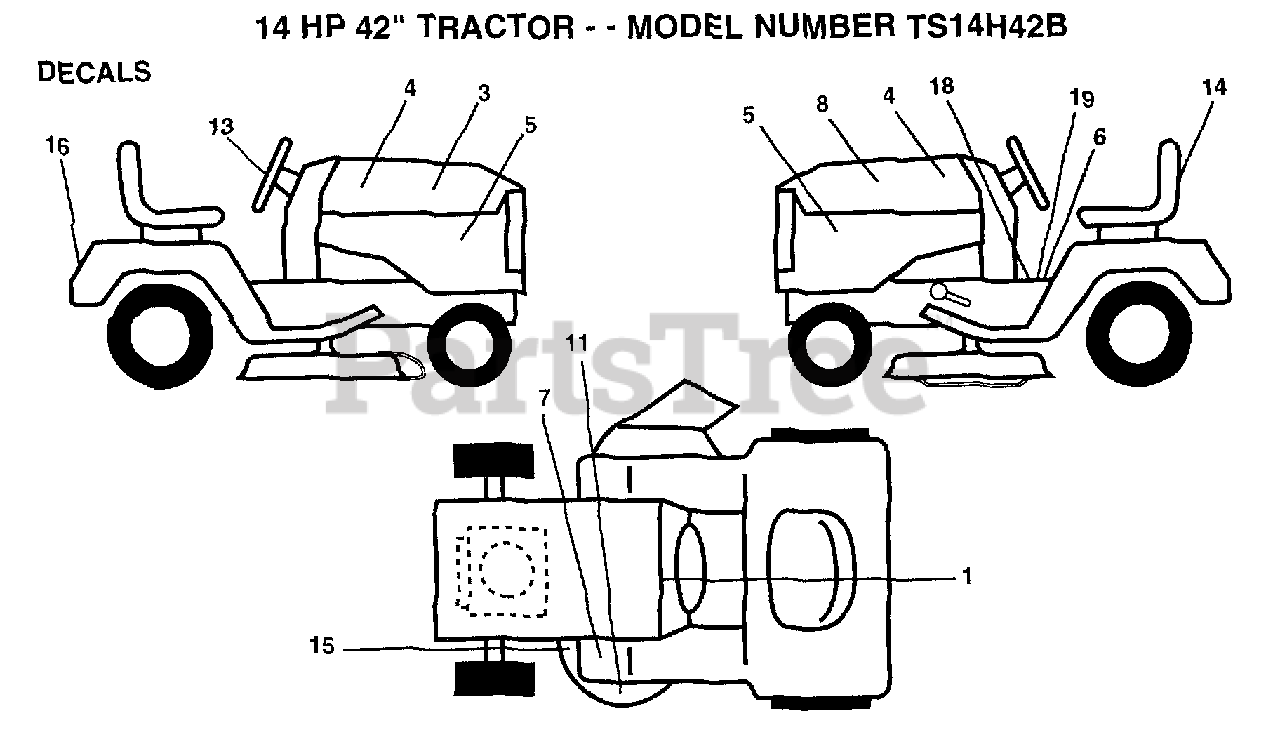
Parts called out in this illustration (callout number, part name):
1	DECAL.DASH.INST.
3	DECAL.HD.RH.14/42
4	NAMEPLATE.HUSK.LG
5	DECAL.PNL.SIDE.14
6	DECAL
8	DECAL.HD.LH.14/42
13	DECAL.INS.STG.WHL
15	DECAL.V.BELT
18	DECAL SADLE HYDRO
19	DECAL BRAK PARK
